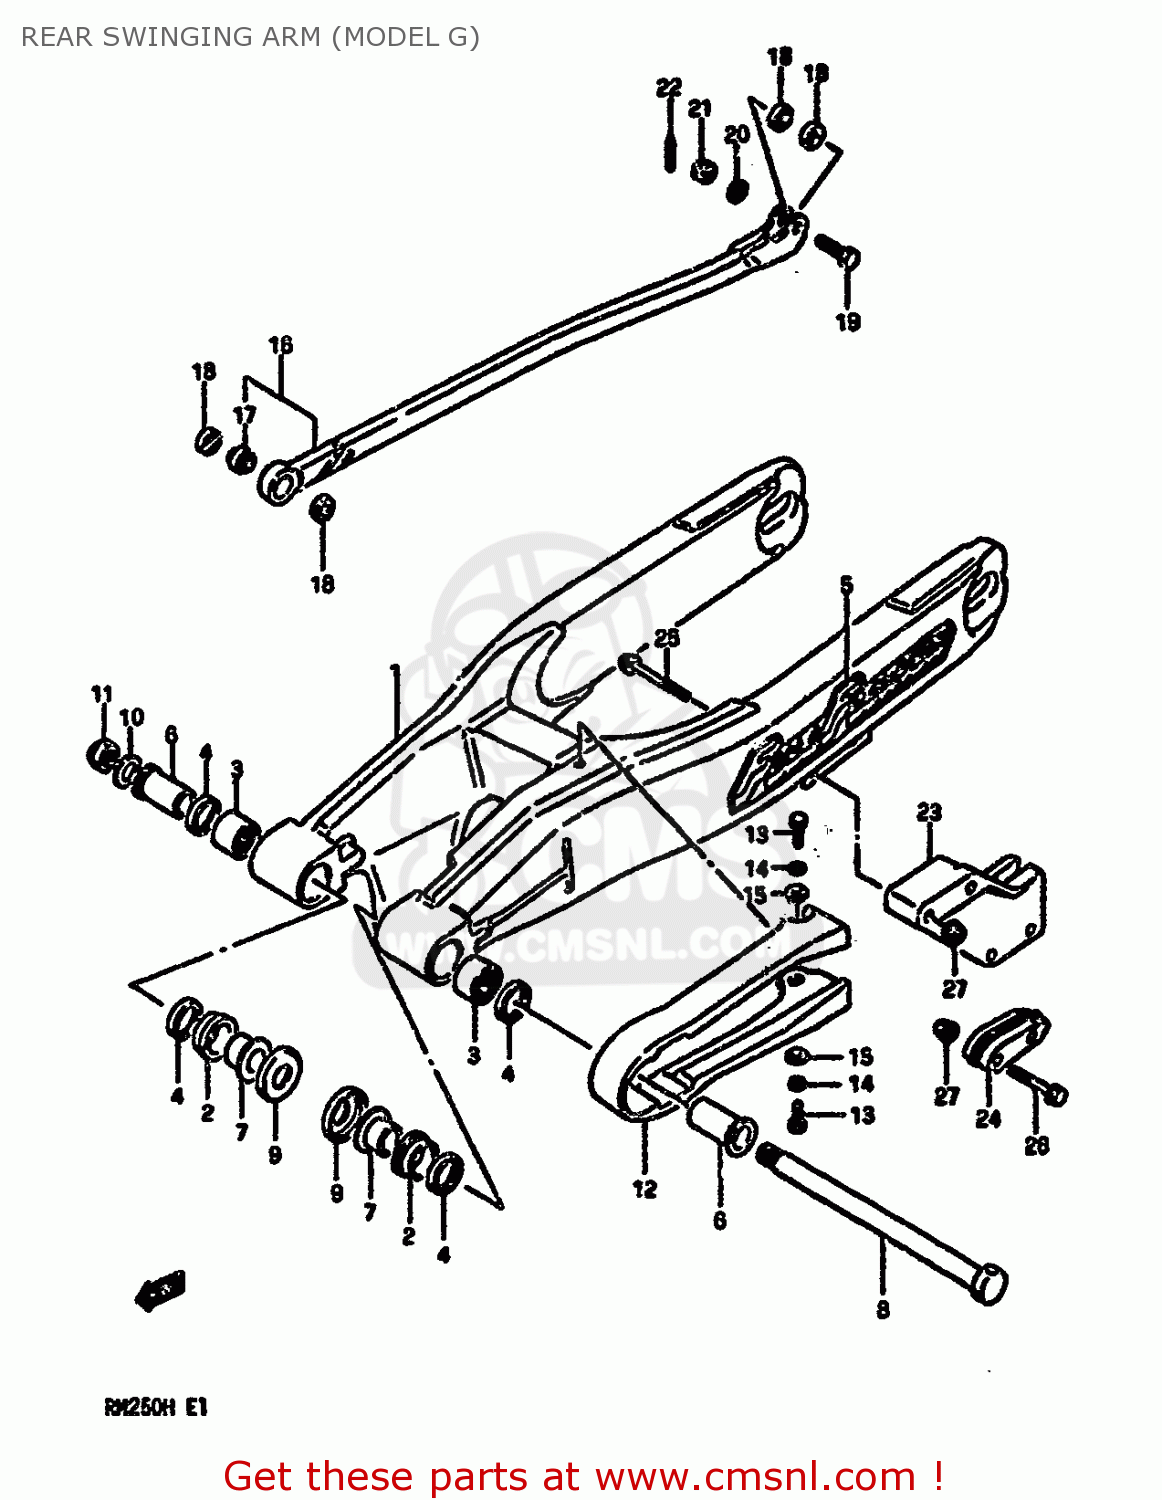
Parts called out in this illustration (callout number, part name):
1	SWING ARM ASSEMBLY,REAR
2	BUSHING,REAR SWING ARM PIVOT
3	BEARING(20X27X20)
4	OIL SEAL
5	LABEL (FRONT CARRIER WARNING)
6	SPACER,RR SWINGING ARM PIVOT
7	SPACER,RR SWGARM PIVOT INNER
8	SHAFT,RR SWINGINGARM PIVOT
9	COVER,RR SWGARM DUST SEAL
10	WASHER(14.5X29X2.3)
11	NUT
12	BUFFER,CHAIN TOUCH DEFLECTOR
13	BOLT
14	WASHER,LOCK
15	WASHER(6.5X16X1.2)
16	TORQUE LINK ASSEMBLY,REAR
17	SPHERICAL BEARING,TORQUE
18	19
19	BOLT 8X29.5
20	WASHER
21	NUT 8MM
22	PIN 20X20
23	GUIDE,CHAIN
24	DEFENSE,CHAIN GUIDE
25	BOLT
26	BOLT,UNDER
27	NUT
